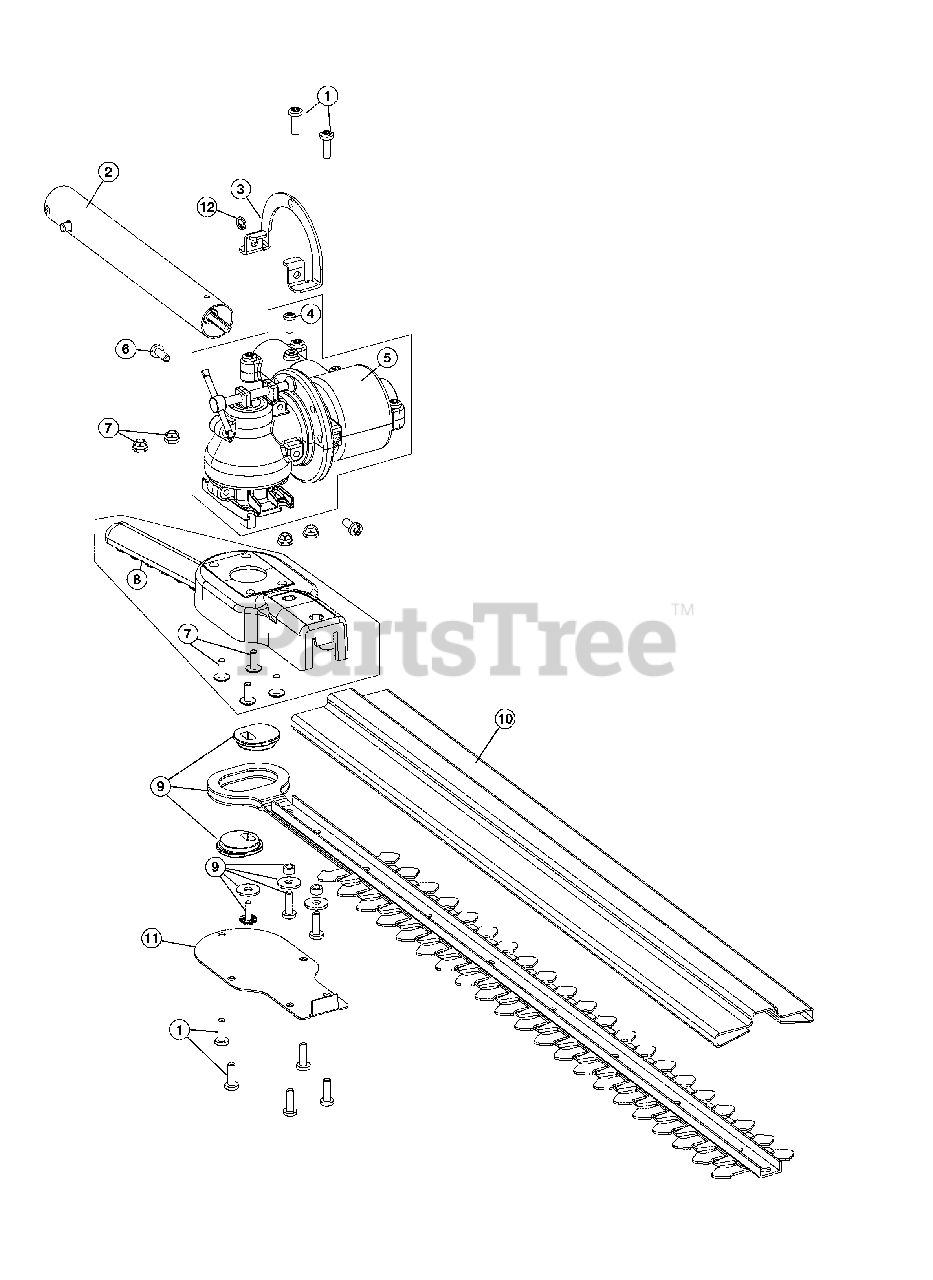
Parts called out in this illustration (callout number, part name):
2	Drive Shaft Housing Assembly
3	Indexing Ring
4	Anti-rotation Screw
5	Gearbox Assembly (includes 4)
7	Blade Housing Hardware
8	Upper Blade Housing (includes 7)
9	Blade Assembly
11	Lower Blade Assembly
12	Lock Washer
